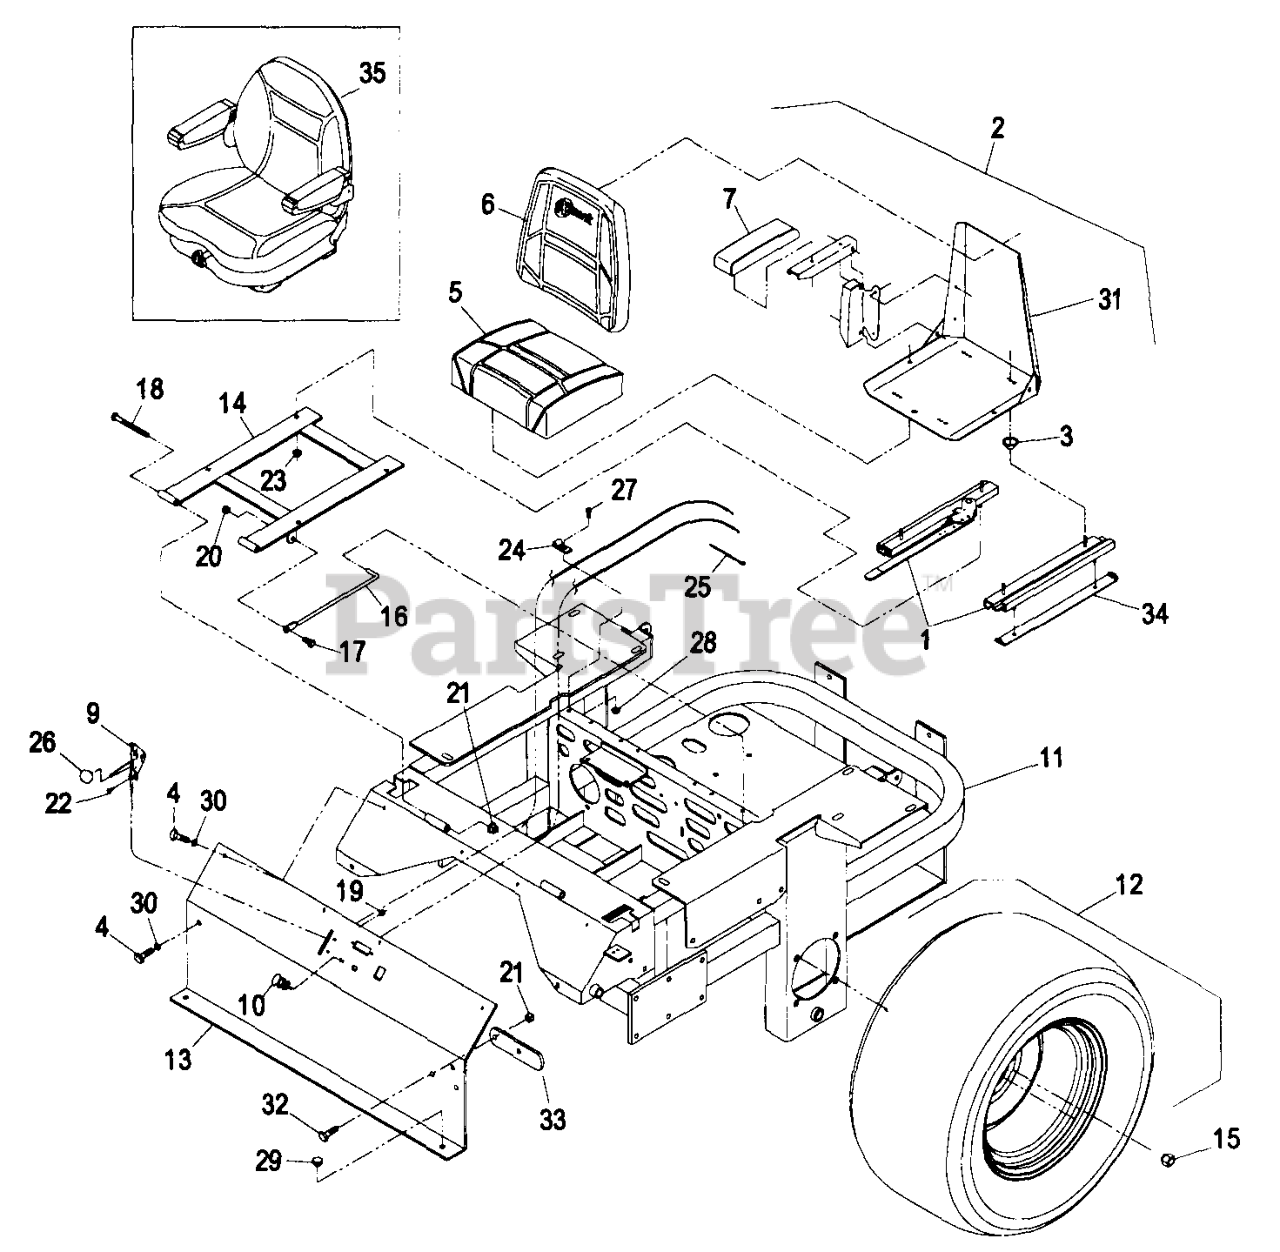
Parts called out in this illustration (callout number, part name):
1	TRACK-SEAT
3	SPACER-TRACK
9	THROTTLE CABLE ASM
10	CONTROL-CHOKE
13	Front, Console
16	ROD-HOLDUP, SEAT
22	BOLT-CARR
24	CLIP-LOOM
25	TIE-PLASTIC
26	KNOB-BALL
31	FRAME-SEAT
33	STOP-BRAKE, PARK
34	STOP-SEAT
